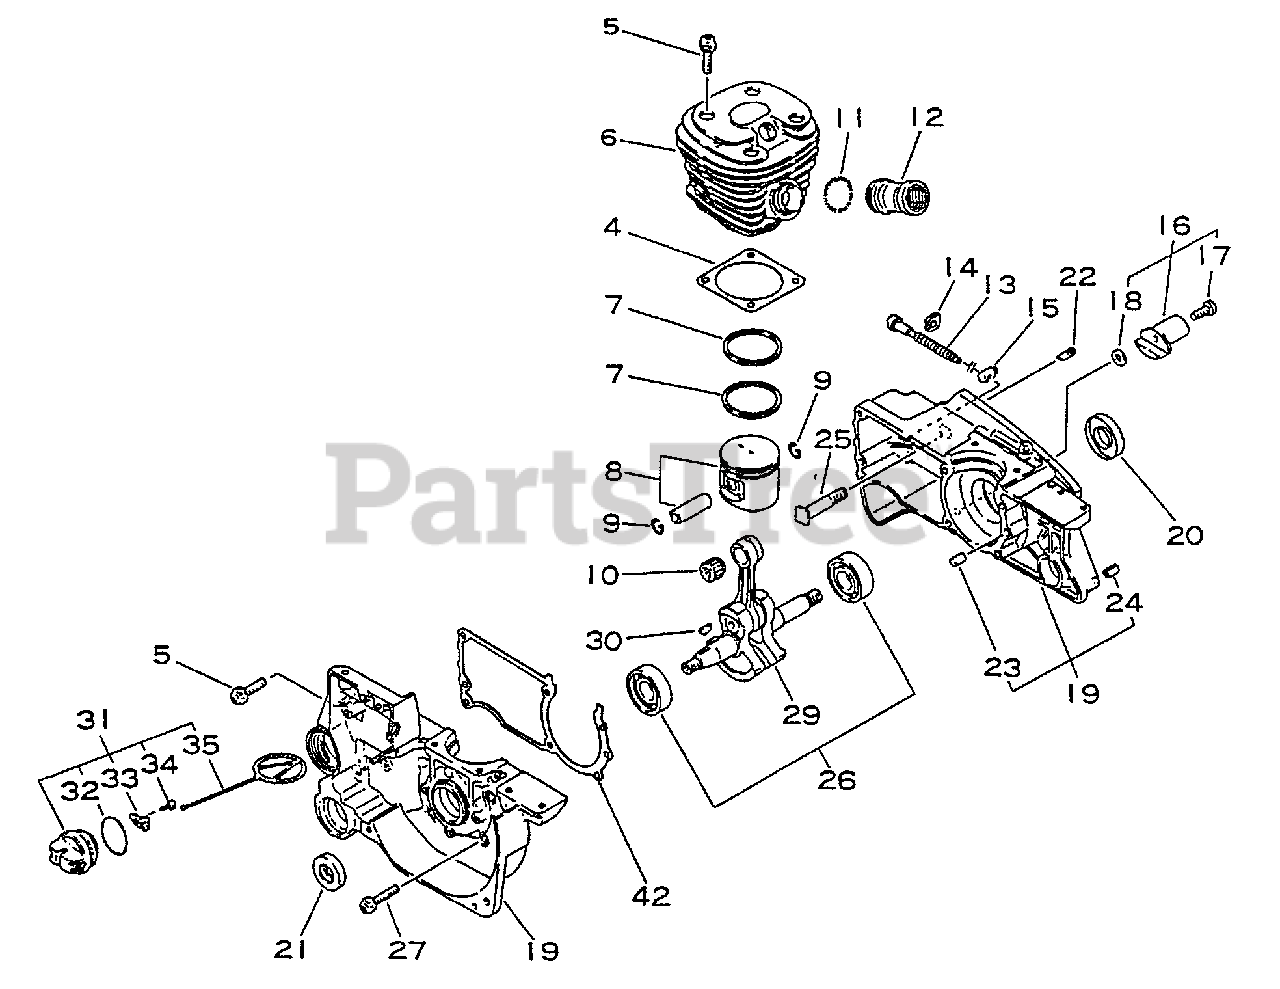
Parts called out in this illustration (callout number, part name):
4	GASKET, CYLINDER
5	BOLT 5×20
6	CYLINDER
7	RING, PISTON
8	PISTON KIT
9	RING, SNAP 8
10	BEARING, NEEDLE
11	BAND
12	ADAPTOR, INTAKE
13	SCREW, CHAIN TENSION
15	TENSIONER, CHAIN
16	CHAIN CATCHER KIT
17	SCREW 5×20
18	WASHER, FLAT 5.5×10×0.8
19	CRANKCASE KIT
20	SEAL, OIL
21	SEAL, OIL
22	VENT ASSY
23	PIN, LOCATING 5×10
24	PIN, SPRING 5×10
25	STUD, GUIDE BAR 8
26	BEARING SET
27	BOLT 5×30
29	CRANKSHAFT ASSY
30	KEY, WOODRUFF
31	CAP ASSY
33	RETAINER, CONNECTOR
34	SCREW, TAPPING 3×8
35	CONNECTOR, CAP L= 60 MM
42	GASKET, CRANKCASE
